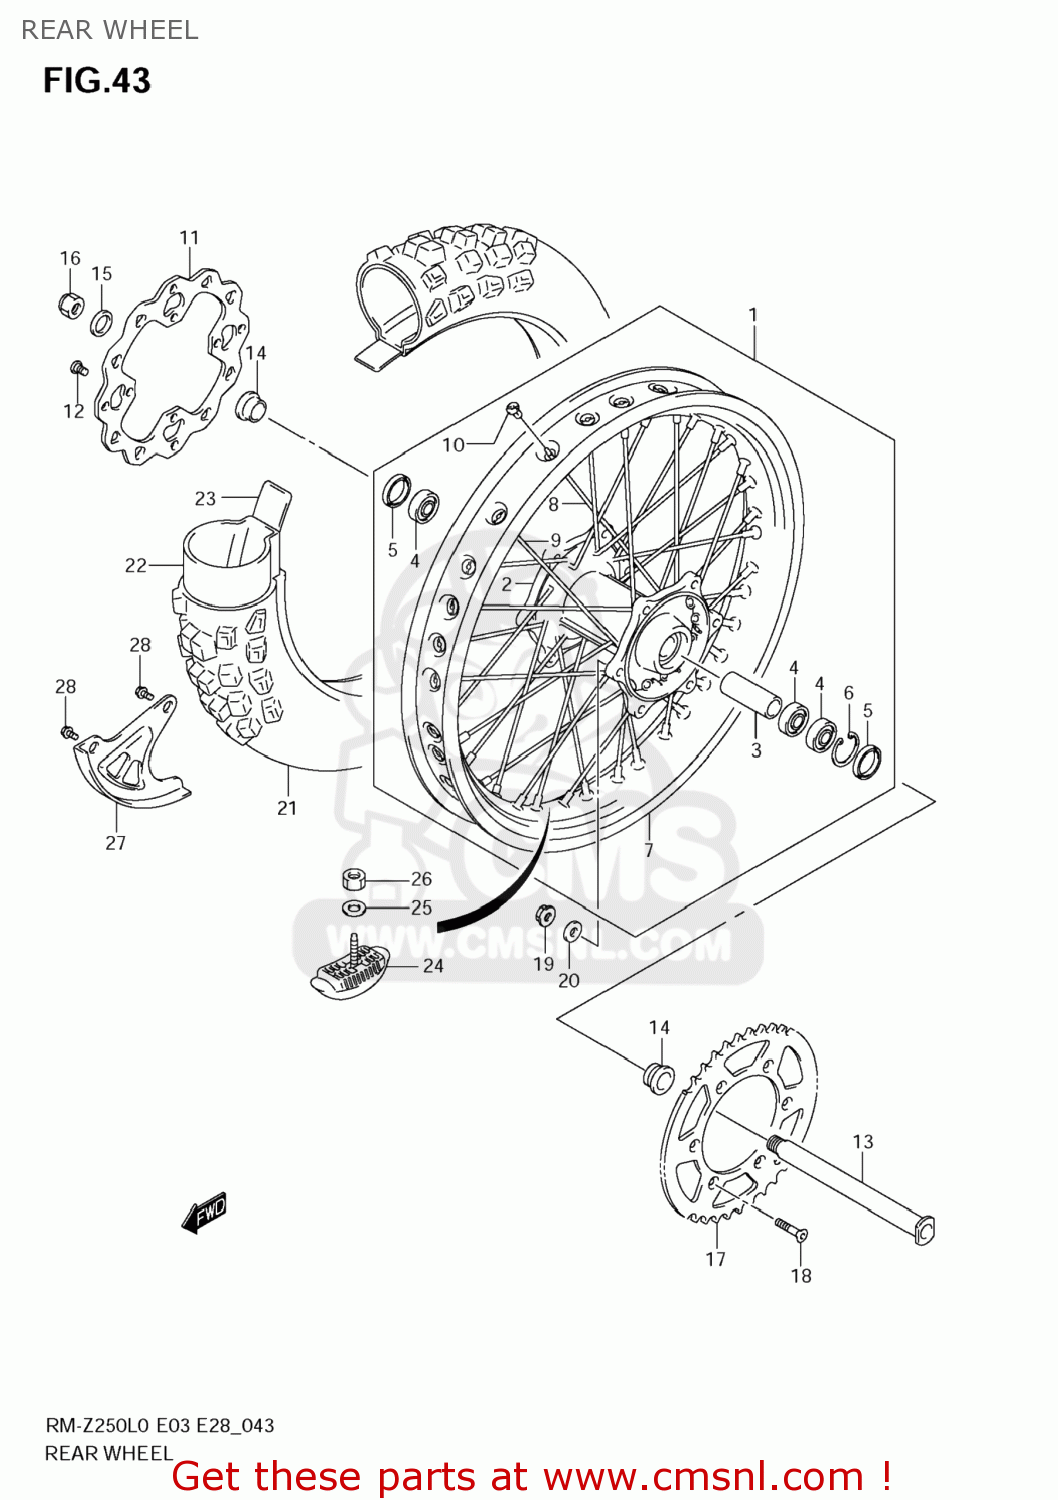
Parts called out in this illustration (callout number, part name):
1	WHEEL ASSY,RR
2	HUB,RR
3	SPACER,RR HUB BEARING
4	BEARING(25X42X9)
5	SEAL,OIL(32X43X7)
6	CIRCLIP
7	RIM,RR WHEEL(19X1.85 AL)(WHT)
8	SPOKE,RR WHEEL INNER
9	SPOKE,RR WHEEL OUTER
10	NIPPLE,RR WHEEL
11	DISC,RR BRAKE
12	SCREW(8X15)
13	AXLE,REAR
14	SPACER,REAR AX
15	WASHER(22X35X2)
16	NUT
17	SPROCKET,RR(NT:49)
18	BOLT(8X28)
19	NUT
20	WASHER(8.5X16X1.2)
21	TIRE,RR(100/90 19)
22	TUBE
23	PROTECTOR,WHL INR TUBE
24	STOPPER,BEAD(1.85)
25	WASHER
26	NUT
27	COVER,REAR DIS
28	BOLT(6X12)
